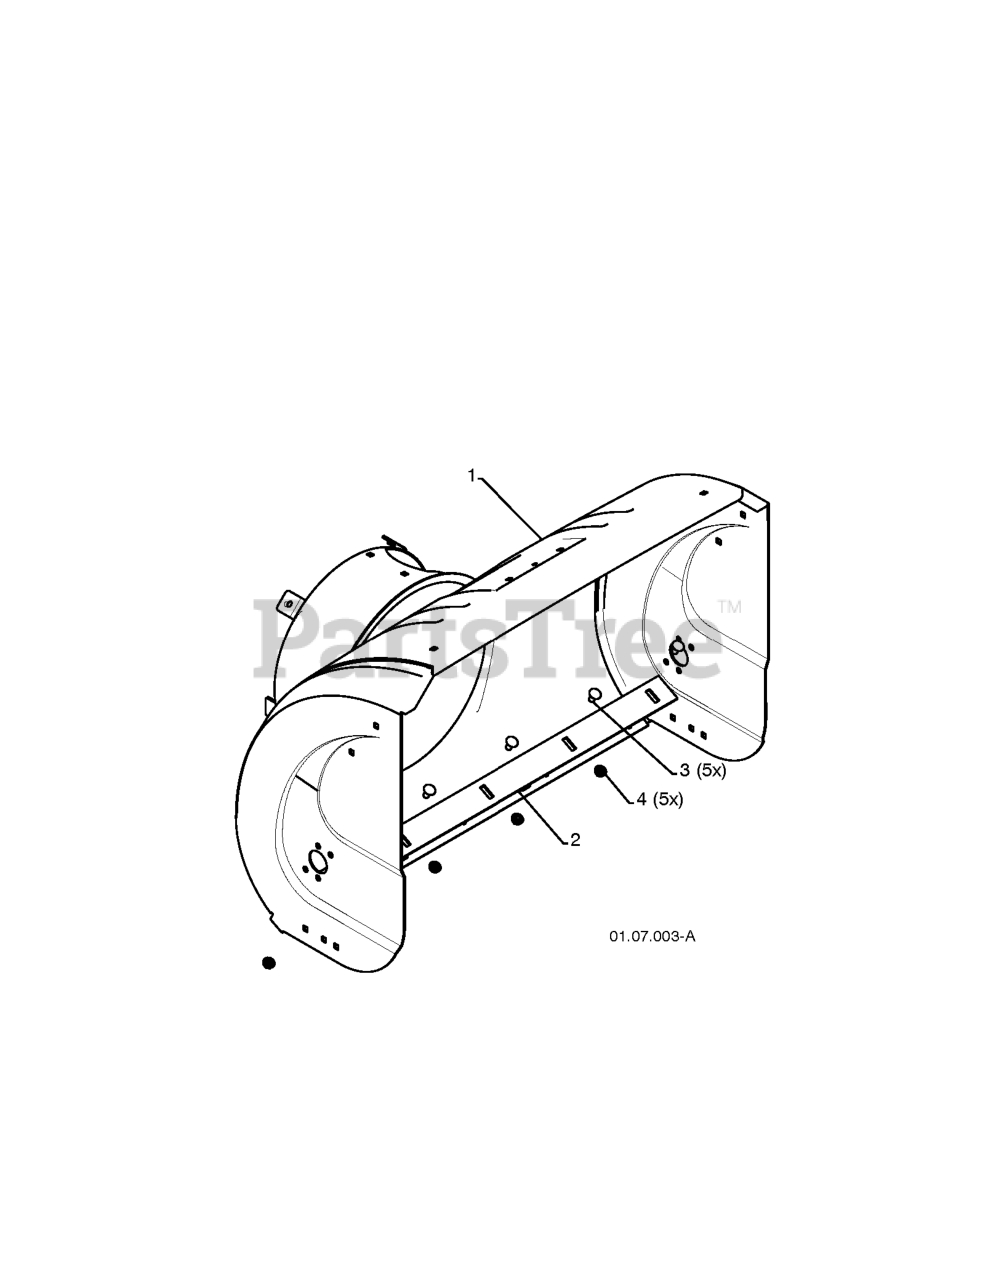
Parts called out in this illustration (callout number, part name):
1	HOUSING.AUG.WELDMENT.27.ORANGE
2	RP BAR.SCRAPER.27.PNT.431
3	BOLT
4	NUT.FLANGE.5/16
